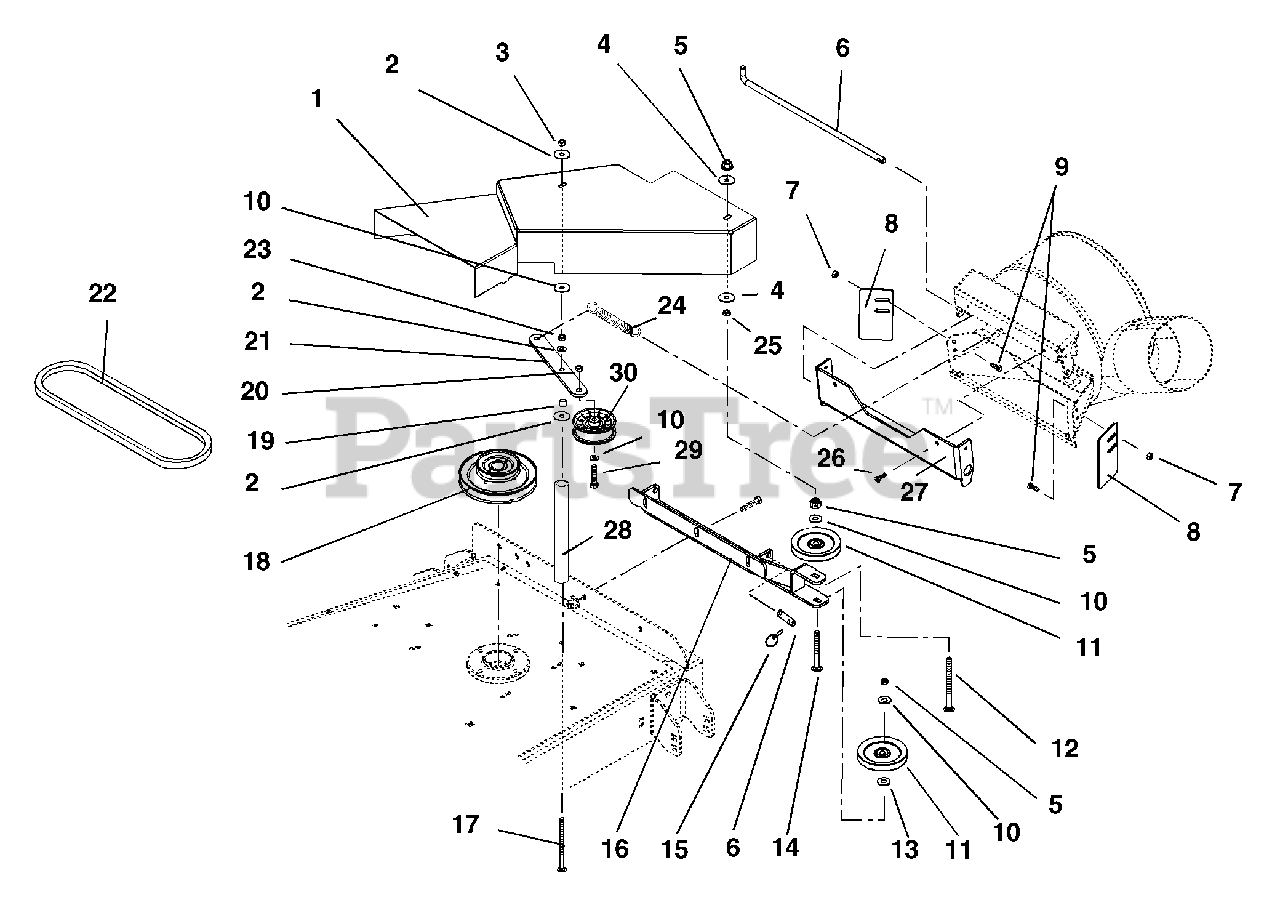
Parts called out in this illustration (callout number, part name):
1	Weldment, Belt Guard
2	Washer-Flat-Steel .344 x 1.125 x.135
3	Nut-Locking-Top-Flange .31-18
4	Washer-Flat-Steel .406 x 1.375 x.135YZ
5	Nut-Locking-Nylon .38-16
6	Rod-Pivot
7	Nut-Locking-Top-Flange .25-20
8	Bar, Extension
9	Bolt-Round Head Square Neck.25-20 x .75
10	Washer-Flat-Steel .438 x 1.00 x.083
11	Idler-V 4.00 x .38
12	Bolt-Round Head Square Neck.38-16 x 2.75 Grade 5
13	Washer-Flat-Steel .406 x 1.00 x .188
14	Bolt-Round Head Square Neck.38-16 x 1.75 Grade 5
15	Pin-Klik 1.00 x .188 x 1.25
15	(Gravely Part Number)
16	Weldment, Pivot Mounting Bracket
17	Bolt-Round Head Square Neck.31-18 x 5 Grade 5
18	Pulley, Double V 3.50/6.25 Dia.
19	Spacer .380 x .503 x .281
19	(Gravely Part Number)
20	Nut-Locking-Top-Flange .38-16
21	Arm, Idler
22	V-Belt, 48-78 78" Outer Circle
23	Nut-Locking-Nylon .312-18
24	Spring-Tension .069 x .62 x 3.50
24	(Gravely Part Number)
25	Nut-Hex .38-16
26	Screw-Tapping .25-20 x .50 Hex Washer Head Thread Rolling
27	Weldment, Blower Mount
28	Spacer .625 x 3.25
29	Bolt-Hex .38-16 x 1.75 Grade 5
30	Idler-Flat 3.00 x .38
